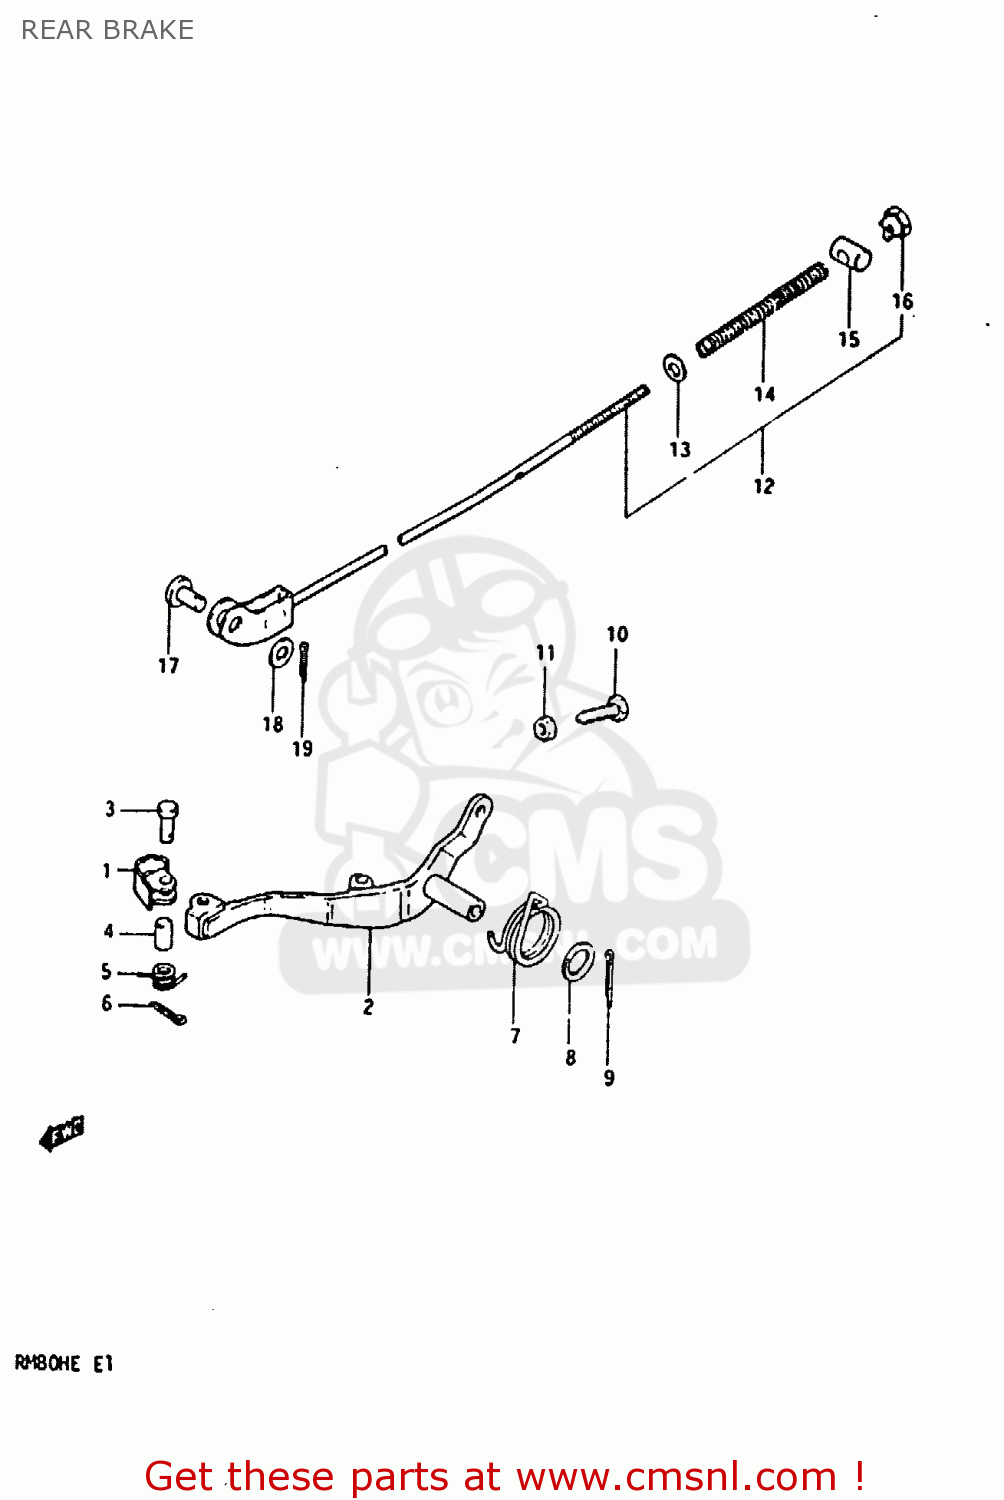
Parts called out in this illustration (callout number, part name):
1	PEDAL,BRAKE
2	ARM,BRAKE PEDAL
3	PIN
4	SPACER(6.5X10.5X6.5)
5	SPRING
6	PIN
7	SPRING
8	WASHER(15.5X26X2.3)
9	COTTER PIN
10	SCREW(6X23)
11	NUT
12	ROD ASSY, REAR BRAKE
13	WASHER
14	SPRING
15	PIN(11X18)
16	NUT (6MM)
17	PIN
18	WASHER
19	PIN 20X20
